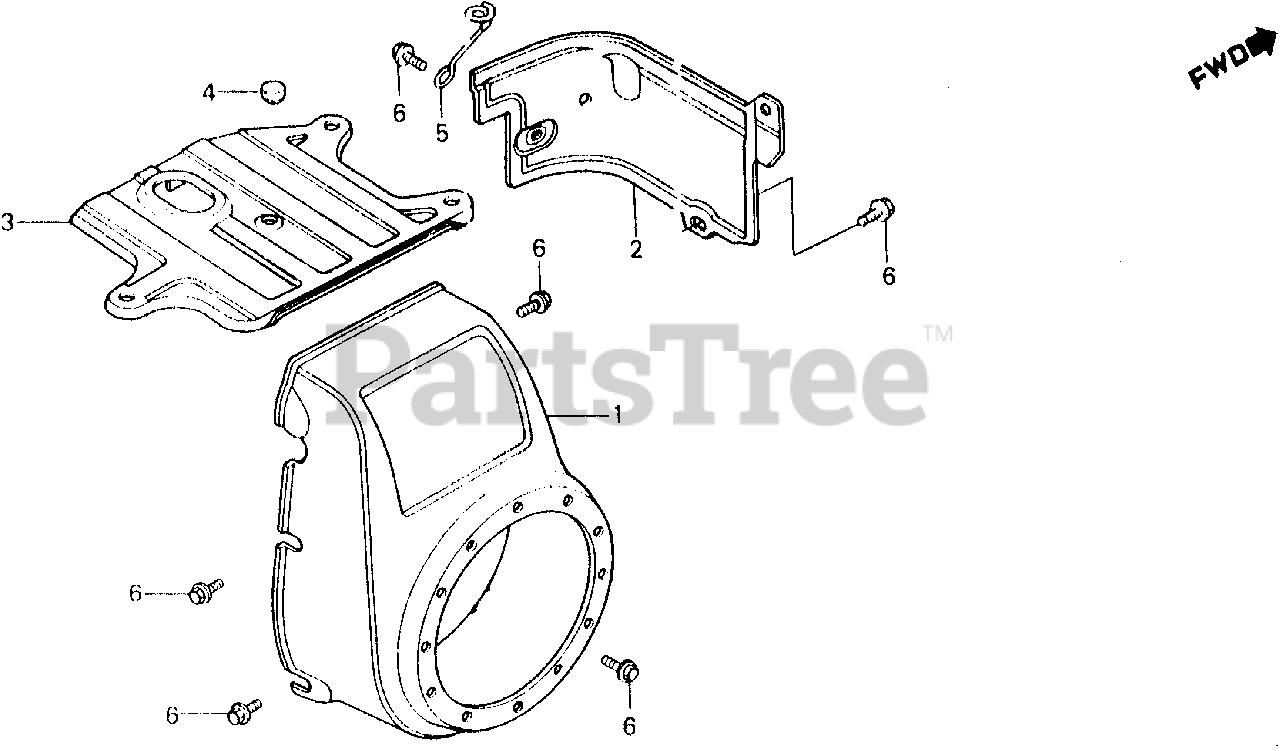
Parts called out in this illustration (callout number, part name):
1	COVER, FAN *R8* (BRIGHT RED)
3	COVER, TOP
4	GROMMET, TOP COVER
5	CLAMP, IGNITION TUBE
6	BOLT, FLANGE (6X12) (CT200)
